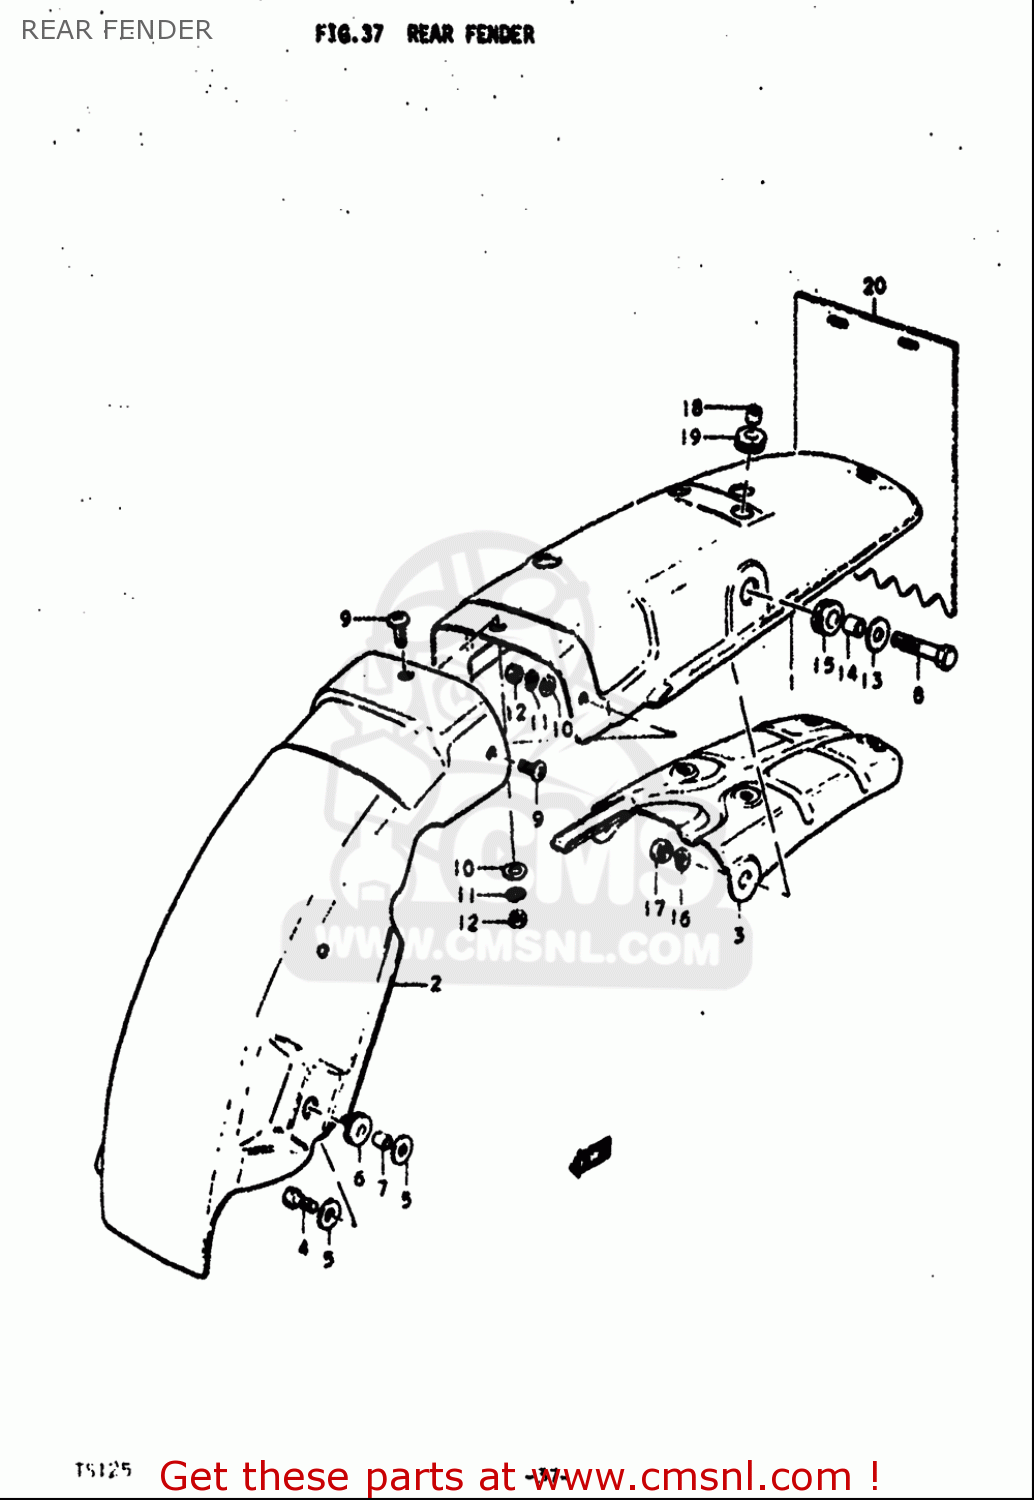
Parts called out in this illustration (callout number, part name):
4	BOLT
5	WASHER(6.5X20X1.2)
7	SPACER(6.1X9X7.5)
8	BOLT
9	SCREW
11	WASHER,LOCK
12	NUT
13	WASHER(10.5X24X1.6)
14	SPACER
15	CUSHION
16	WASHER,LOCK
17	NUT
18	SPACER(6.1X9X7.5)
19	CUSHION
